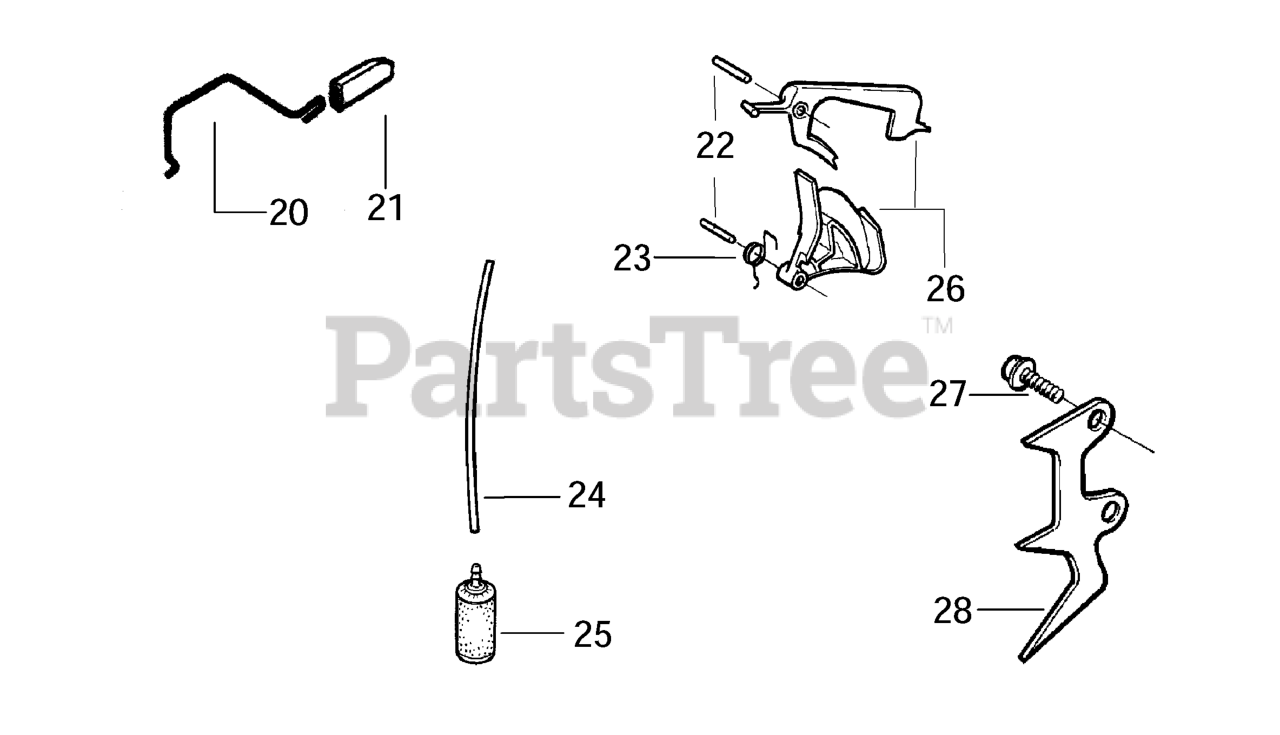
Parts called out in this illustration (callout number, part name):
20	THROTTLE SHAFT 36/41
21	THROTTLE ACTUATOR 36/41
22	PIN,TRIGGER 36/41
23	TRIGGER SPRING 36/41
24	HOSE. FUEL
25	FUEL PICK-UP
26	THROTTLE TRIGGER-KIT
27	SCREW-10-14 X 1/2 PLASTITE
28	SPIKE 36/41
